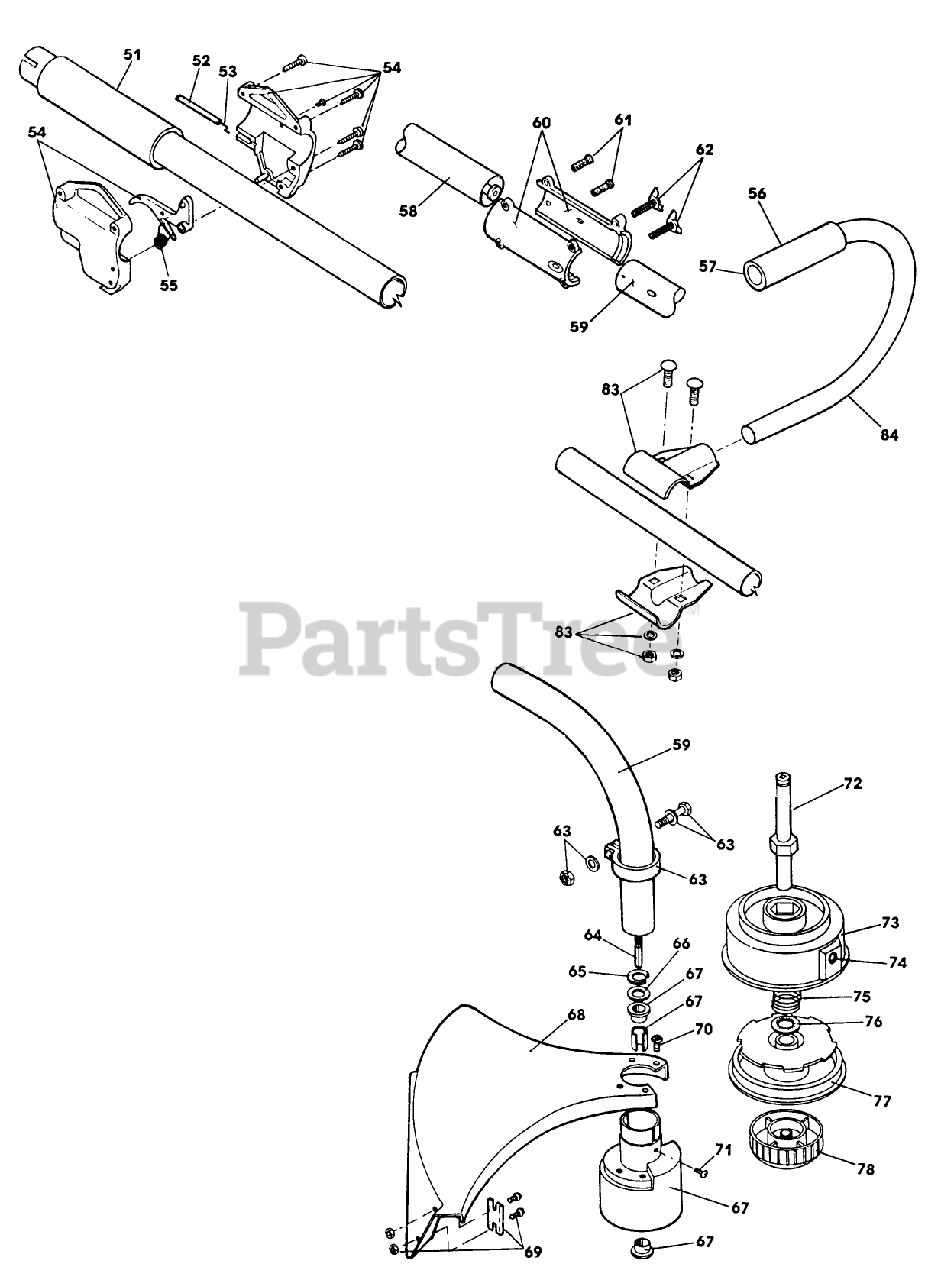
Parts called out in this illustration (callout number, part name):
53	THROTTLE CABLE WIRE
54	THROTTLE TRIGGER ASM
55	THROTTLE TRIGGER SPRING
56	HANDLE NITRILE GRIP
57	TUBE CLOSURE
62	ADJUSTMENT KNOB SET
65	RETAINING RING
67	BUSHING HSG ASM
69	BLADE ASM
70	GUARD MOUNTING SCREW
71	ANTI-ROTATION SCREW
76	RETAINER WASHER
77	REEL - INNER
